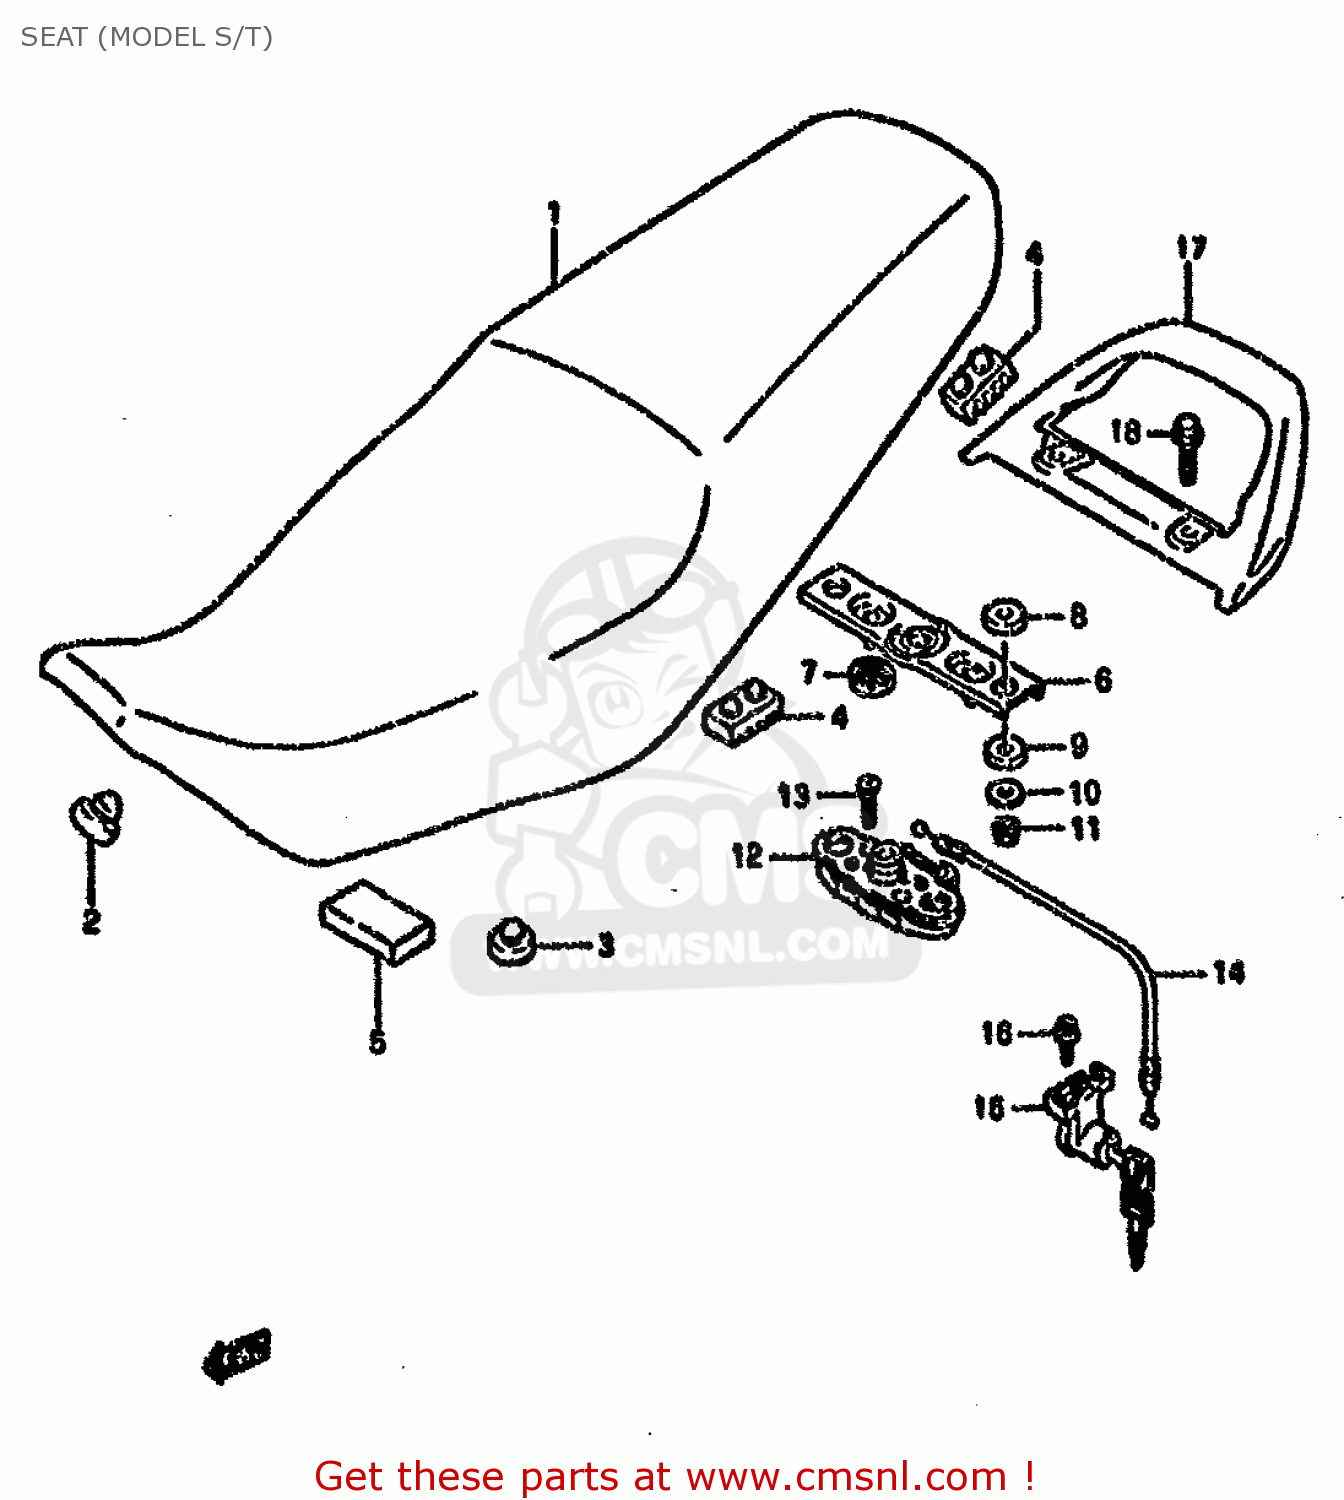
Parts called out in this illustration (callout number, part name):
1	SEAT SET
2	CUSHION
3	CUSHION
4	CUSHION,SEAT(40X20X15)
5	CUSHION(30X60X10)
6	STRIKER,SEAT LOCK
7	CUSHION,SEAT LOCK(10X22X6)
8	CUSHION,UPR
9	CUSHION,LWR
10	WASHER
11	NUT
12	LOCK ASSY,SEAT STRIKER
13	SCREW
14	CABLE,SEAT LOCK
15	LOCK SET,SEAT
16	SCREW
17	BOLT
18	HANDLE,PILLION RIDER
19	BOLT
